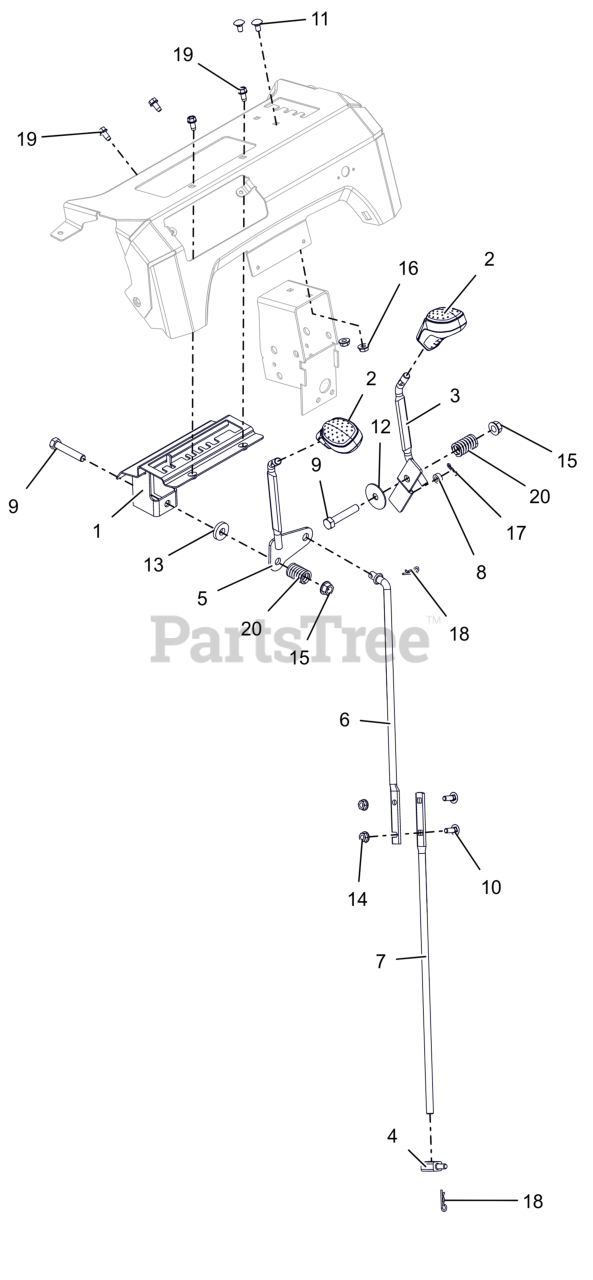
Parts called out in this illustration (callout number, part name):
1	WELDMENT, DETENT PLATE-COMPACT
2	KNOB, CONTROL, DASH
3	WELDMENT,SM DASH DEFL CONTROL
4	PIVOT,SHIFT ROD .375-16(TRUNN)
5	LEVER, CONTROL-SHIFT(WELDMENT)
6	ROD, SHIFT - UPPER
7	ROD, SHIFT-LOWER (SM DASH DLX)
8	BSHG-SLV .265X.500X.219
9	BLT,HEX .38-16X2.00 G5 ZCC
10	BLT, RHSN .25-20X.750 G5 ZCC
11	BLT, RHSN .25-20X.500 G5 ZCC
12	WSHR,FLT .380X1.50X.062 ZCC
13	WSHR, FLT .406X1.00X.188 ZCC
14	NUT-LK-CTR-FLG .25-20 ZC120
15	NUT-LK-TOP-FLG .38-16 ZC120
16	NUT-LK-TOP-FLG .250-20 GF ZCC
17	PIN, HAIR #178 .06X.77 ZCC
18	PIN, HAIR #213 .08X1.19 ZCC
19	SCR-TAP .25-20X.50 HWH ZCC
20	SG-COMP .125X.781X1.250
